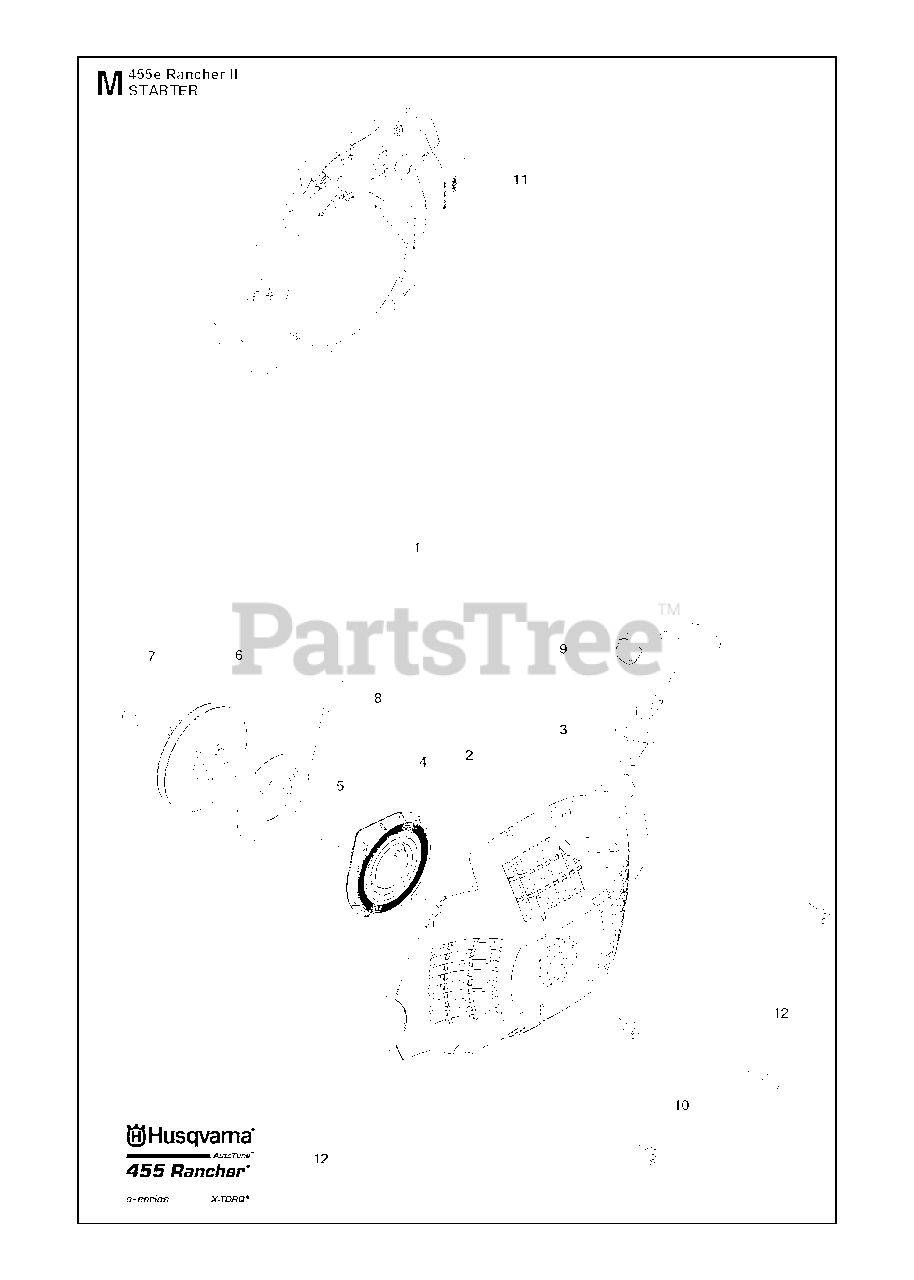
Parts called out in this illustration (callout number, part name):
1	STARTER ASSY
2	STARTER HOUSING
3	SLEEVE
4	SPRING CASSETTE ASSY
5	SCREW
6	PULLEY
7	SCREW
8	STARTER ROPE
9	HANDLE
11	AIR BAFFLE
